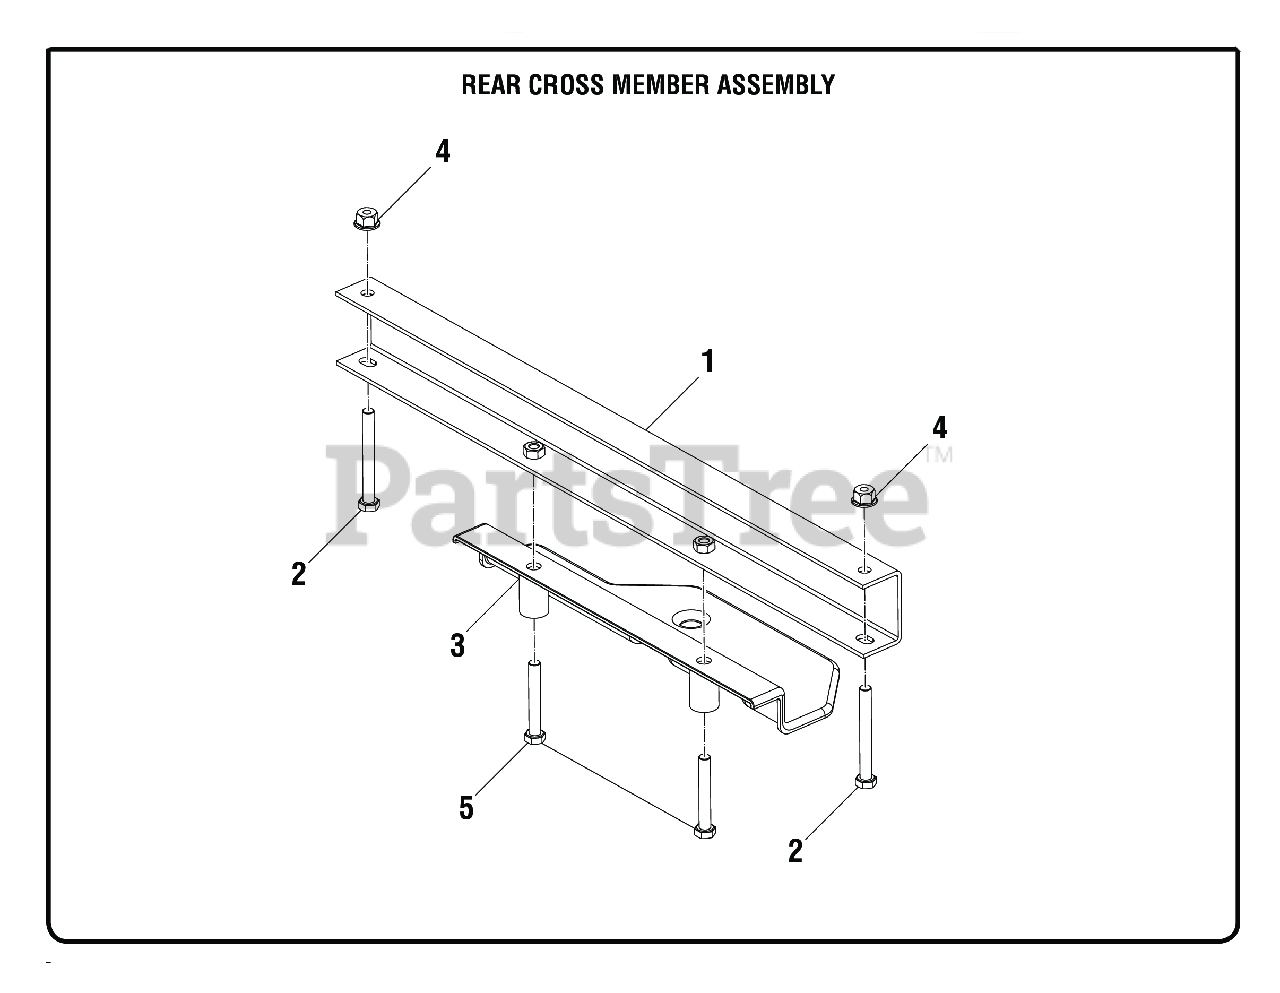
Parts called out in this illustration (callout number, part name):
1	Rear Cross Member, Frame
2	Bolt (M8 x 70 mm, Hex Hd.)
3	Tow Hitch
4	Flange Nut (M8) (For Drive Motor Controller V)
5	Bolt (M8 x 55 mm, Hex Hd.)
